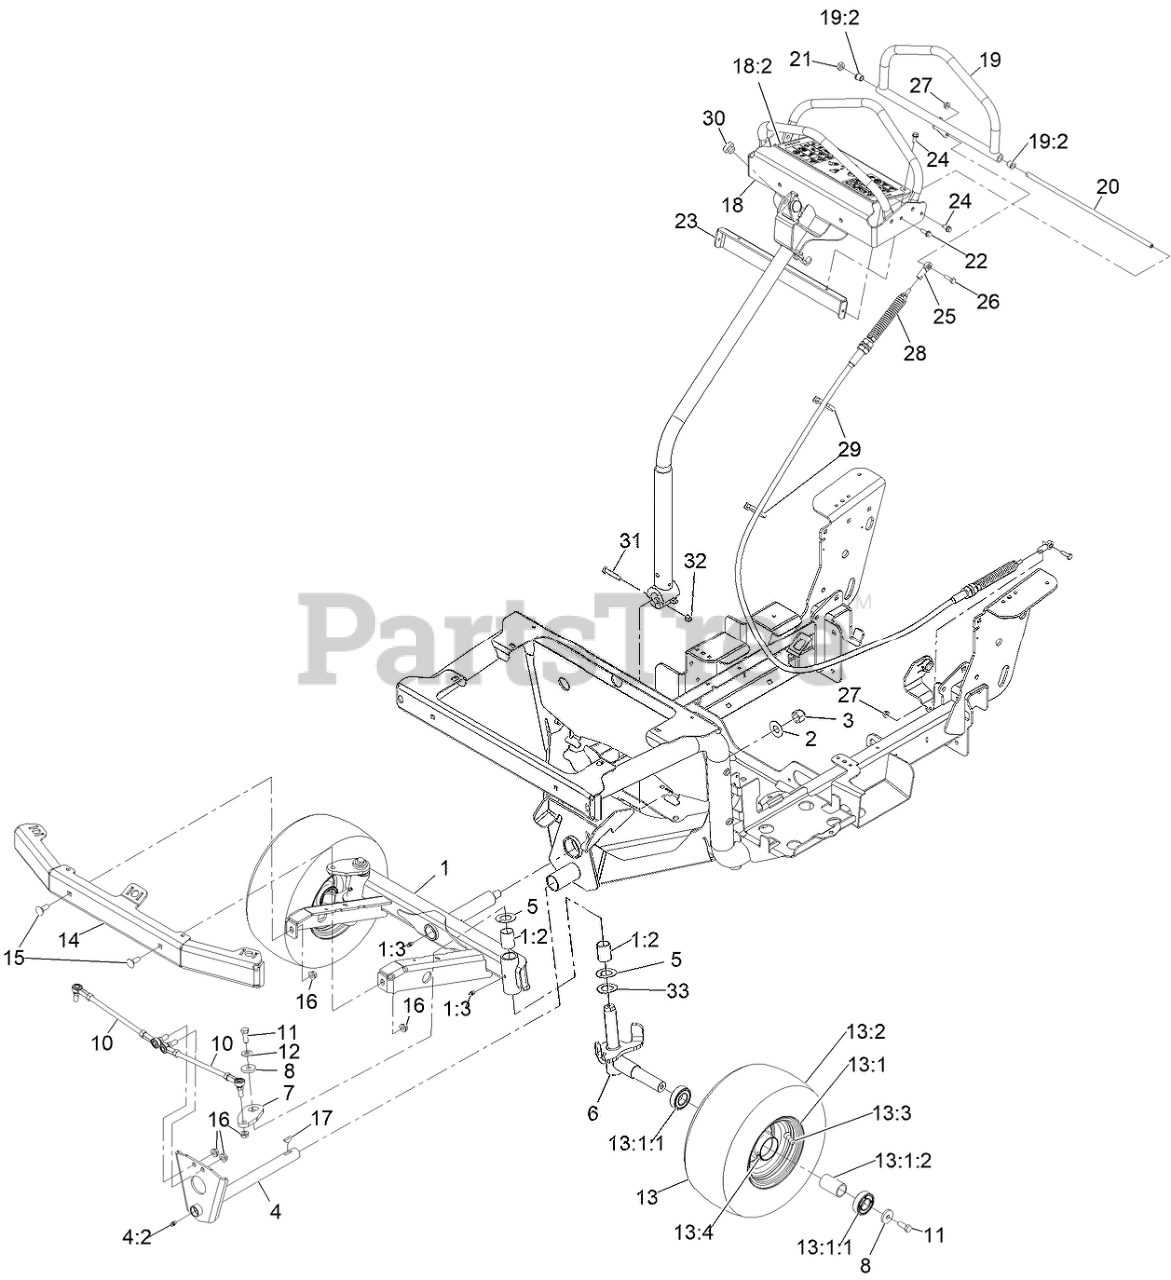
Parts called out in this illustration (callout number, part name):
1	FRONT AXLE ASM
1:2	BEARING-SLEEVE
1:3	ZERK-GREASE
2	WASHER-FLAT
3	NUT-HEX, NI
4	STEERING SHAFT ASM
4:2	ZERK-GREASE
5	WASHER-THRUST
6	FRONT AXLE ASM
7	ARM-STEERING
10	STEERING LINKAGE ASM
11	SCREW-HH
12	WASHER-BELLEVILLE
13	Wheel And Tire ASM
13:1	Wheel ASM
13:1:1	BEARING-BALL
13:3	Stem-Valve
13:4	FITTING-GREASE
14	BUMPER-FRONT
15	SCREW-CARR
17	KEY-WOODRUFF
18	Motion Handle ASM
18:2	DECAL-WARNING
19	Motion Handle ASM
19:2	BEARING
20	SHAFT-PIVOT, SPEED CONTRO
21	SPACER-SHAFT, DRIVE LEVER
22	SCREW-HHF
23	PANEL-REAR, STEERING
24	SCREW-HWH
25	ROD END-BALL JOINT
26	SCREW-HH
28	CABLE-MOTION
29	TIE-CABLE
30	BUMPER-RUBBER
31	Screw-HH
32	NUT-HEX
33	SPACER-RELIEF
